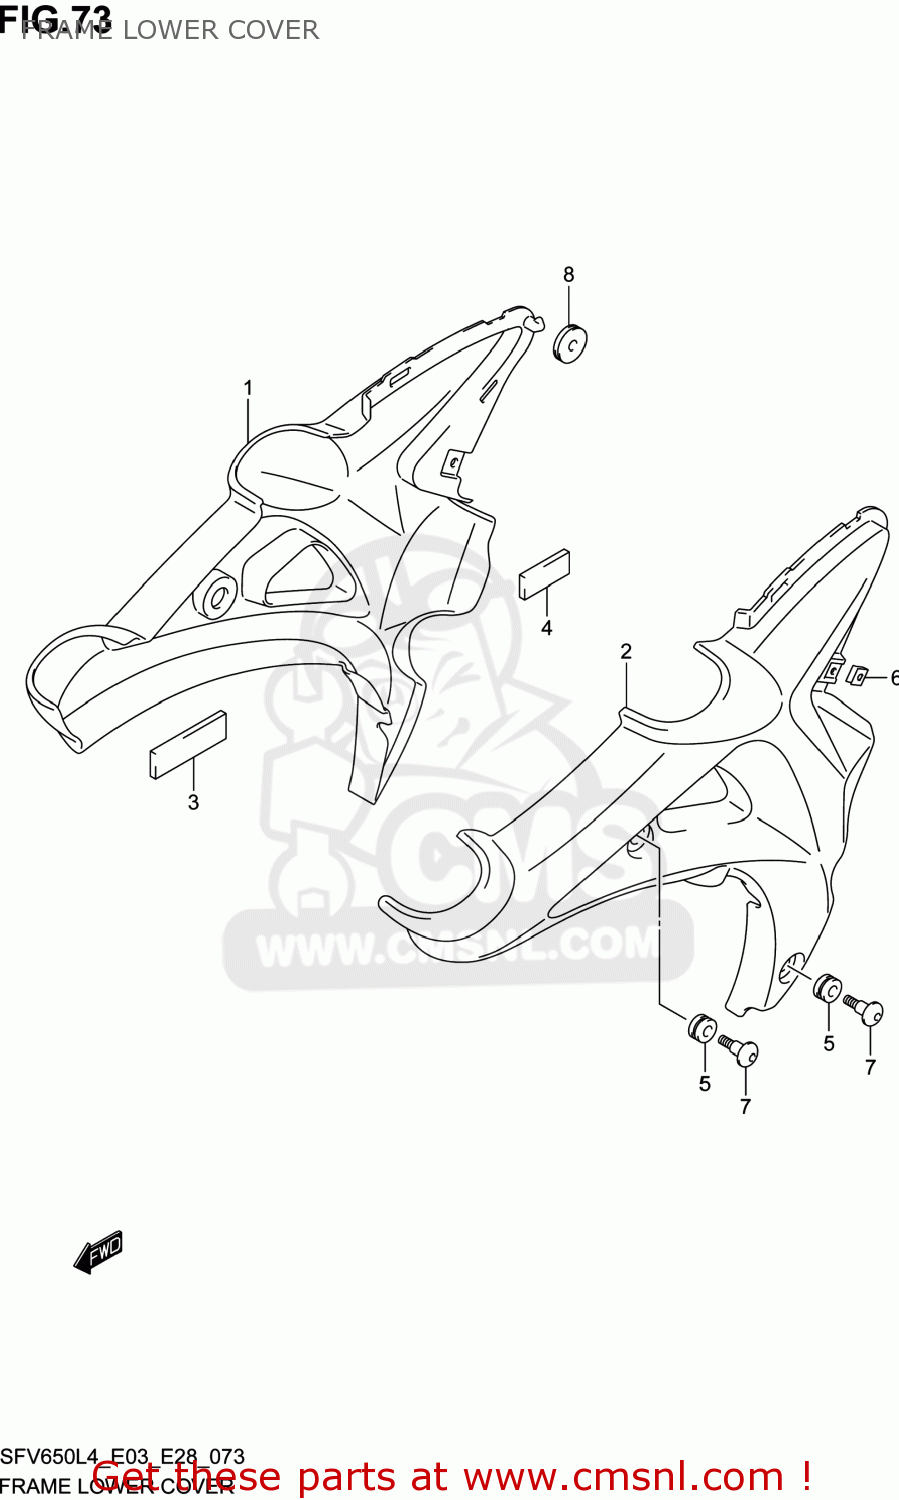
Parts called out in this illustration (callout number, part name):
1	COVER,FRAME LWR,R
2	COVER,FRAME LWR,L
3	CUSHION,FRAME COVER LWR NO.1
4	CUSHION,FRAME COVER LWR NO.2
5	CUSHION
6	NUT
7	SCREW(6X20)
8	CUSHION
